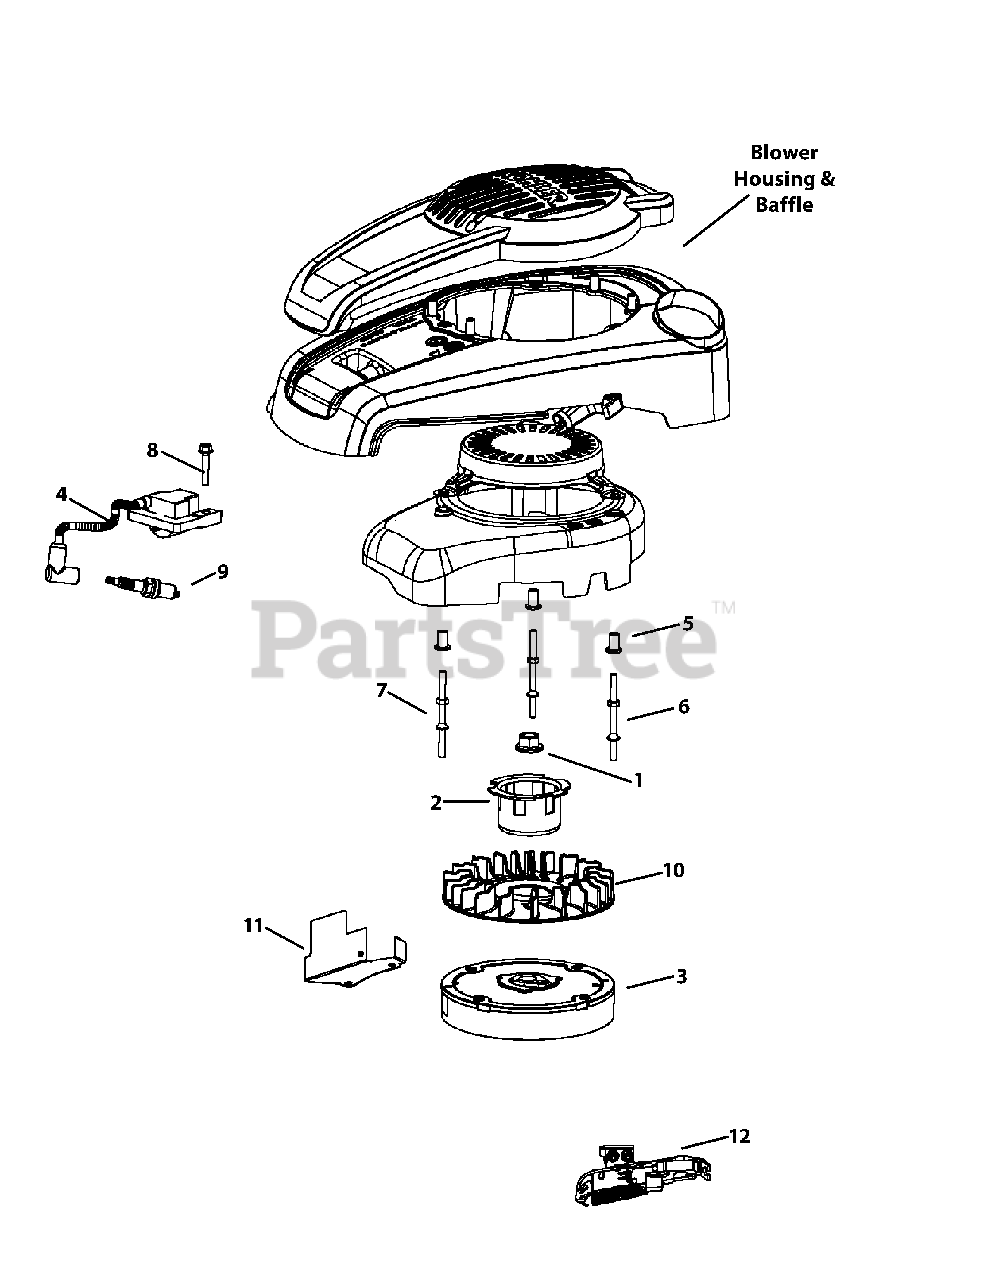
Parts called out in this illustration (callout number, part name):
1	Flywheel Nut w/ Serrations
3	Flywheel Assembly (Aluminum)
4	Ignition Module (Alum STD)
6	Stud
7	Stud
8	Hex Flange Screw, M6
9	Spark Plug
10	Flywheel Fan
12	Carb Side Brake Assembly
